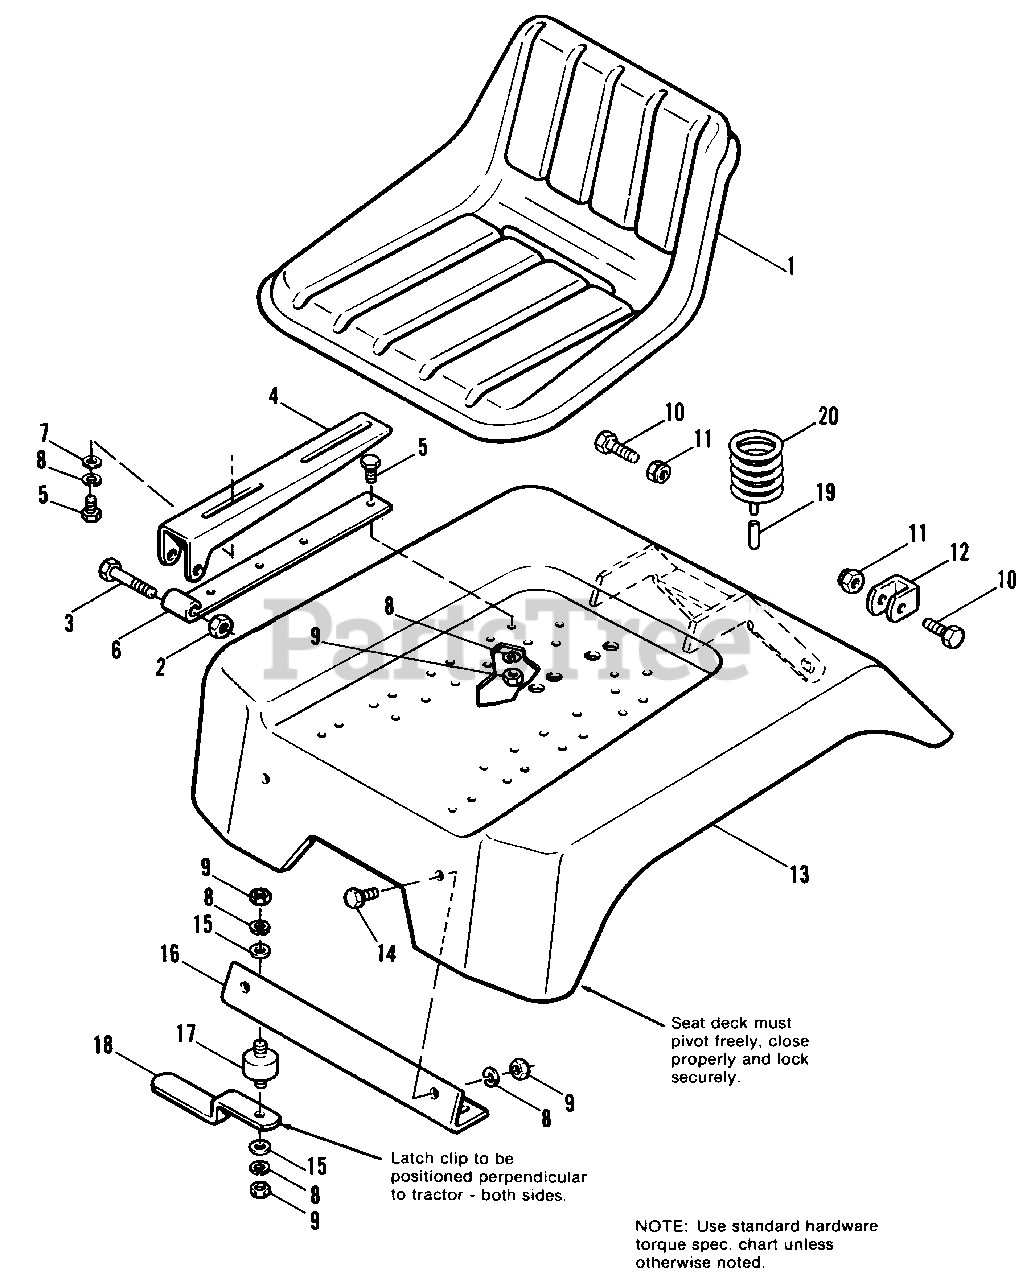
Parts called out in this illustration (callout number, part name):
2	LOCKNUT, Hex, Full, 3/8-16
3	CAPSCREW, Hex Hd., 3/8-16 x 2
4	HINGE, Upper
5	CAPSCREW, Hex Hd., 5/16-18 x 3/4
6	HINGE, Lower
7	WASHER, Plain, 5/16
8	LOCKWASHER. 5/16
9	NUT, Hex, 5/16-18
10	CAPSCREW, Hex, Hd., 3/8-16 x 1-1/4
11	LOCKNUT, Hex, 3/8-16
12	STOP, Seat Deck
13	DECK ASSY., Seat
14	CAPSCREW, Hex, Hd., 5/16-18 x 5/8
15	WASHER, 1/4
16	BRACKET, Front Seat Deck
17	CONNECTOR. Cushion
18	CLIP, Latch
19	COVER, Wire
20	SPRING, Seat
